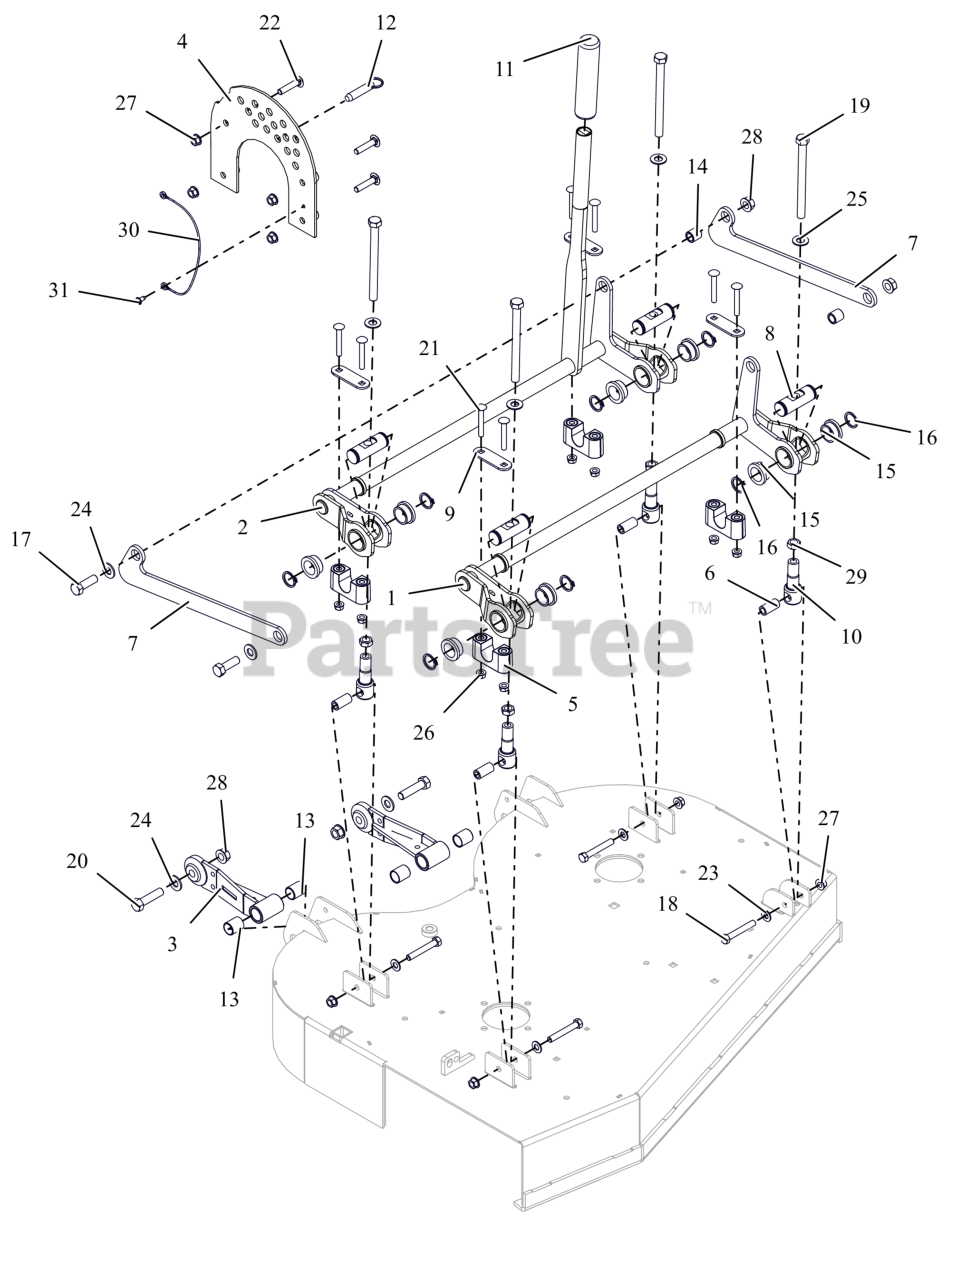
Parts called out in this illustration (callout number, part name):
1	WLDMT, DECK LIFT
2	WLDMT, DECK LIFT
3	WLDMT, PUSHER LINK BAR
4	WLDMT, DECK INDEXING (RED)
5	ASM-BUSHING, DECK LIFT
6	SPACER, DECK LEVELING
7	LINK, DECK LIFT
8	PIN, DECK LIFT
9	PLATE, BEARING SUPPORT
10	LINK, DECK LIFT FORMED
11	GRIP, DECK LIFT
12	PIN, .500 x 2.000 USABLE LG BALL
13	BRG, .750 X .875 X 1.000
14	BSHG, SLV .510 X .751 X .750
15	BSHG,FLG 1.0 X 1.25 X 1.5 X .6
16	RG-RTNG-EXT 1.00X.078
17	BLT,HEX .50-13X1.50 G5 ZCC
18	BLT, HEX .38-16X2.50 G5 ZCC
19	BLT, HEX .50-13X6.00S G5 ZCC
20	BLT, HEX .50-13X2.00 G8 ZCC
21	BLT, RHSSN.31-18X2.25 G5 ZCC
22	BTL,RHSSN .375-16 X 1.75 G5 ZCC
23	WSHR,FLT .406X.812X.065 ZCC
24	WSHR,FLT .531X1.062X.095 ZCC
25	WSHR, FLT .557X1.040X.102 ZCC
26	NUT,LK-CTR-FLG .31-18 GF ZCC
27	NUT-LK-CTR-FLG .375-16 GF ZCC
28	NUT-LK-CTR-FLG .500-13 GG ZCC
29	NUT-JAM .500-13 G2 ZCC
30	CABLE, 12.0 LANYARD, NYLON
31	SCR-TAP .25-20X.50 HWH ZCC
